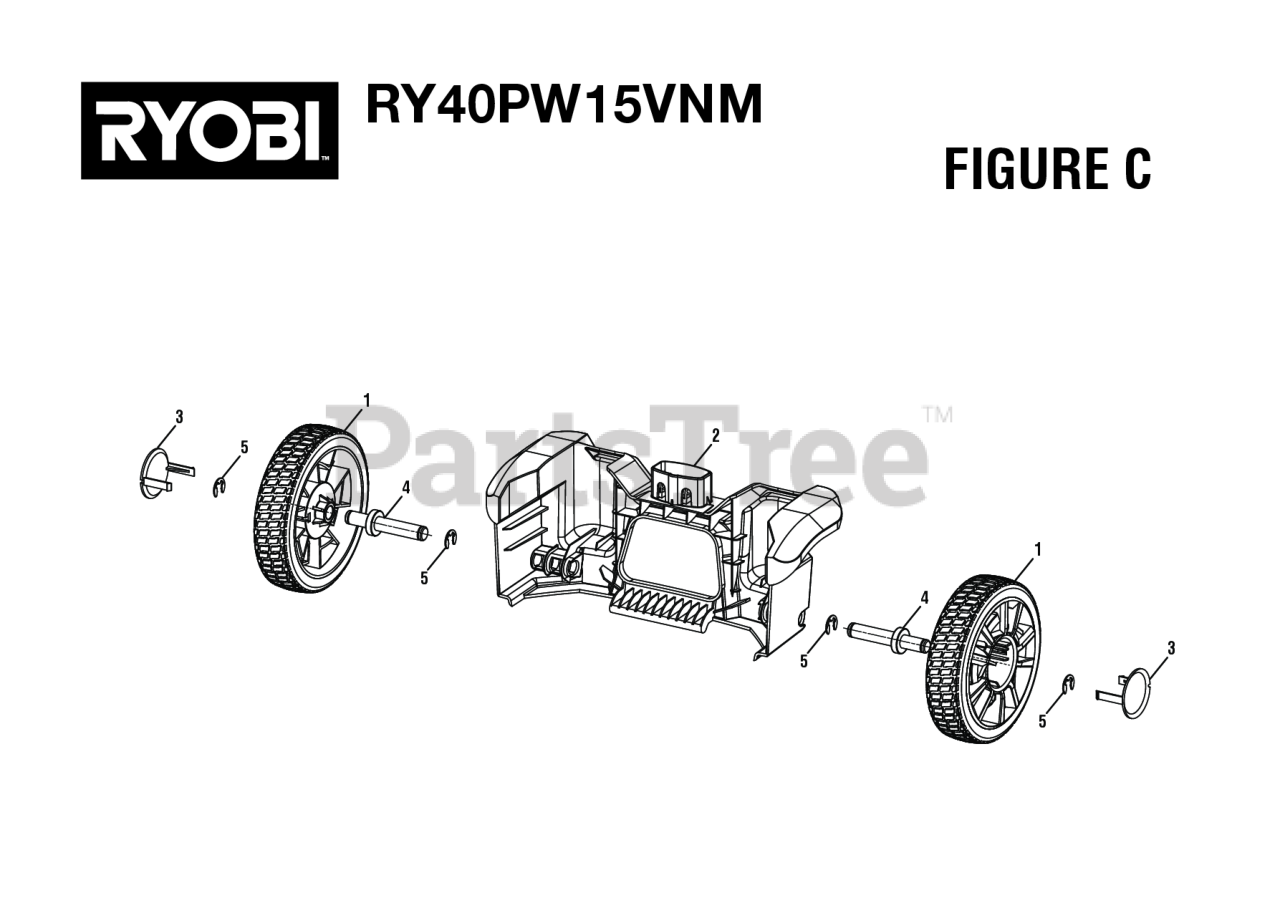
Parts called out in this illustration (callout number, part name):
2	Wheel Base Bracket
3	Wheel Cover
4	Wheel Axle
5	Retaining Ring
